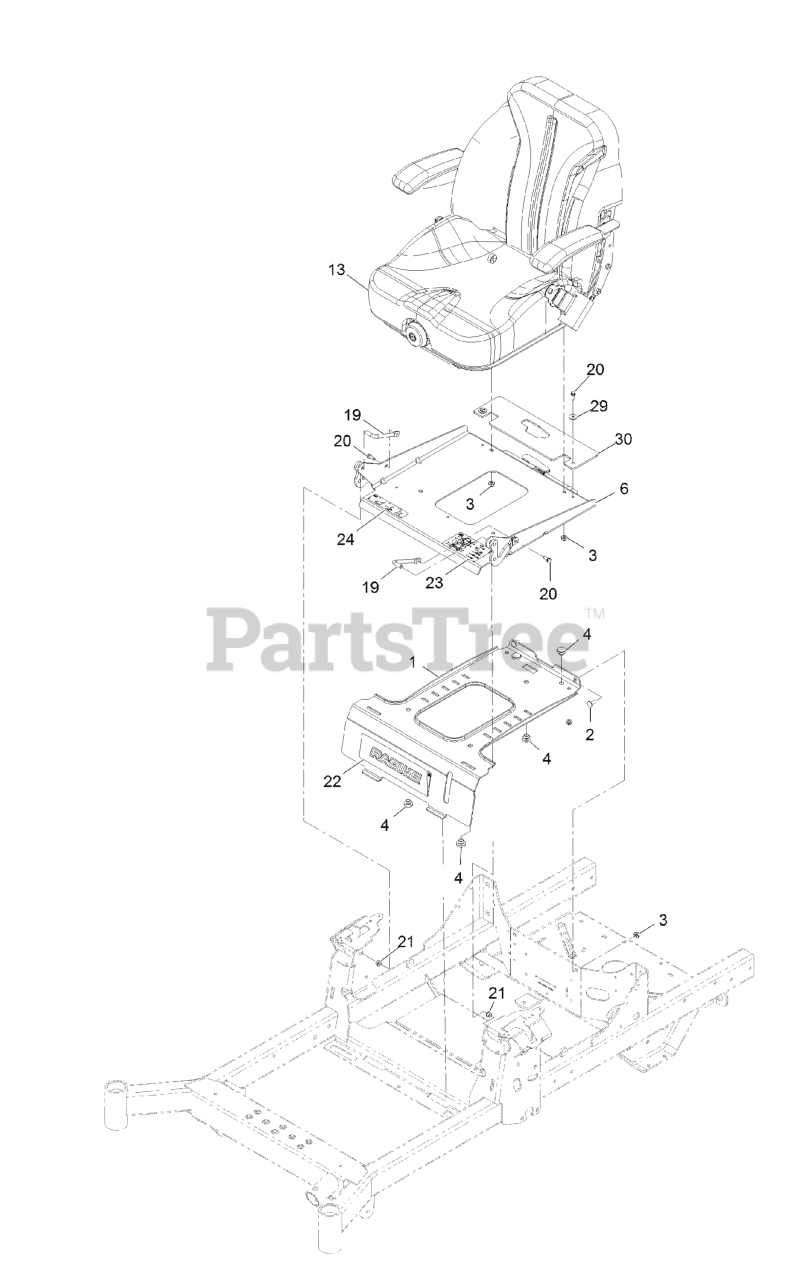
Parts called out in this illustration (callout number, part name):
1	PLATE-RETAINER, TANK
2	SCREW-CARR
3	NUT-HF, NI
4	BUMPER-SEAT
6	SEAT PAN AND LATCH ASM
13	ASM-SUSP SEAT
19	PIN-PIVOT, SEAT
20	SCREW-HWH, THREAD ROLL
21	BUSHING-FLANGED
22	DECAL-RADIUS LOGO
23	DECAL-AID, SERVICE
24	DECAL-LATCH, SEAT
30	GUARD-SEAT, RUBBER
